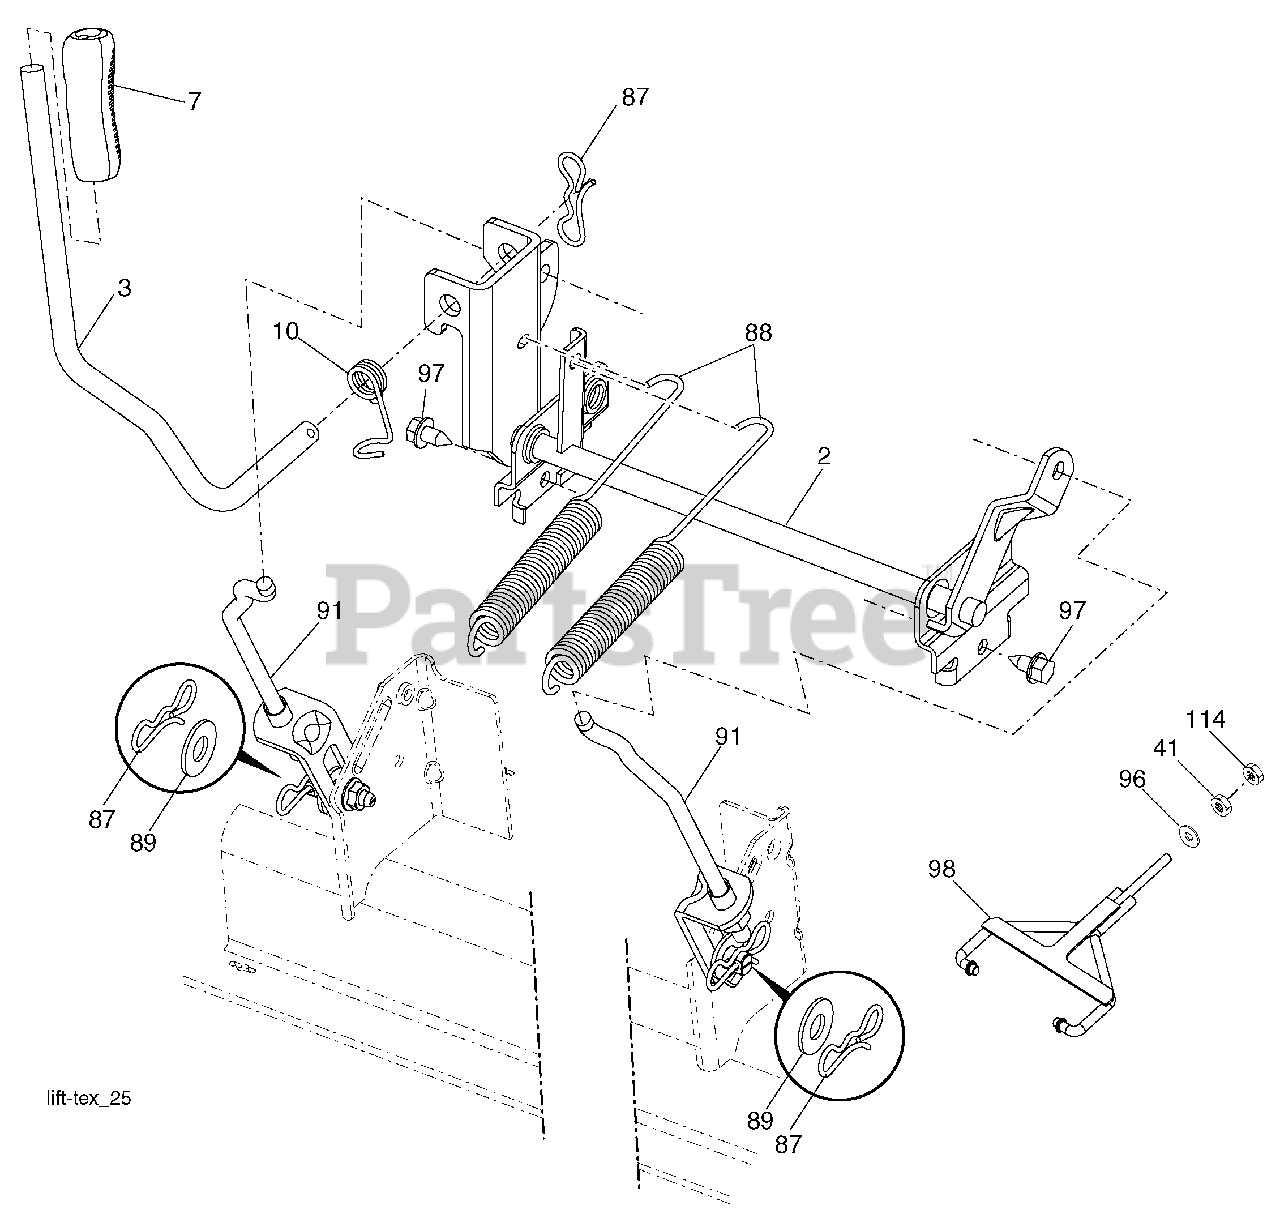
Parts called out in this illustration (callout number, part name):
2	Shaft Asm., Lift
3	Lever Asm., Lift RH
7	Grip, Lever
10	Spring Torsion
41	Nut lift Link 7/16-20
87	Pin Cotter 7/16 Bow Tie Lock
88	Spring Lift Assist
89	Washer Clear Zinc
91	Link Lift Susp Mower Rear
96	Bushing Spherical
97	Screw 3/8-16 x 3/4
98	Link Lift Front Deck Susp
114	Nut Hex Jam 7/16-20
